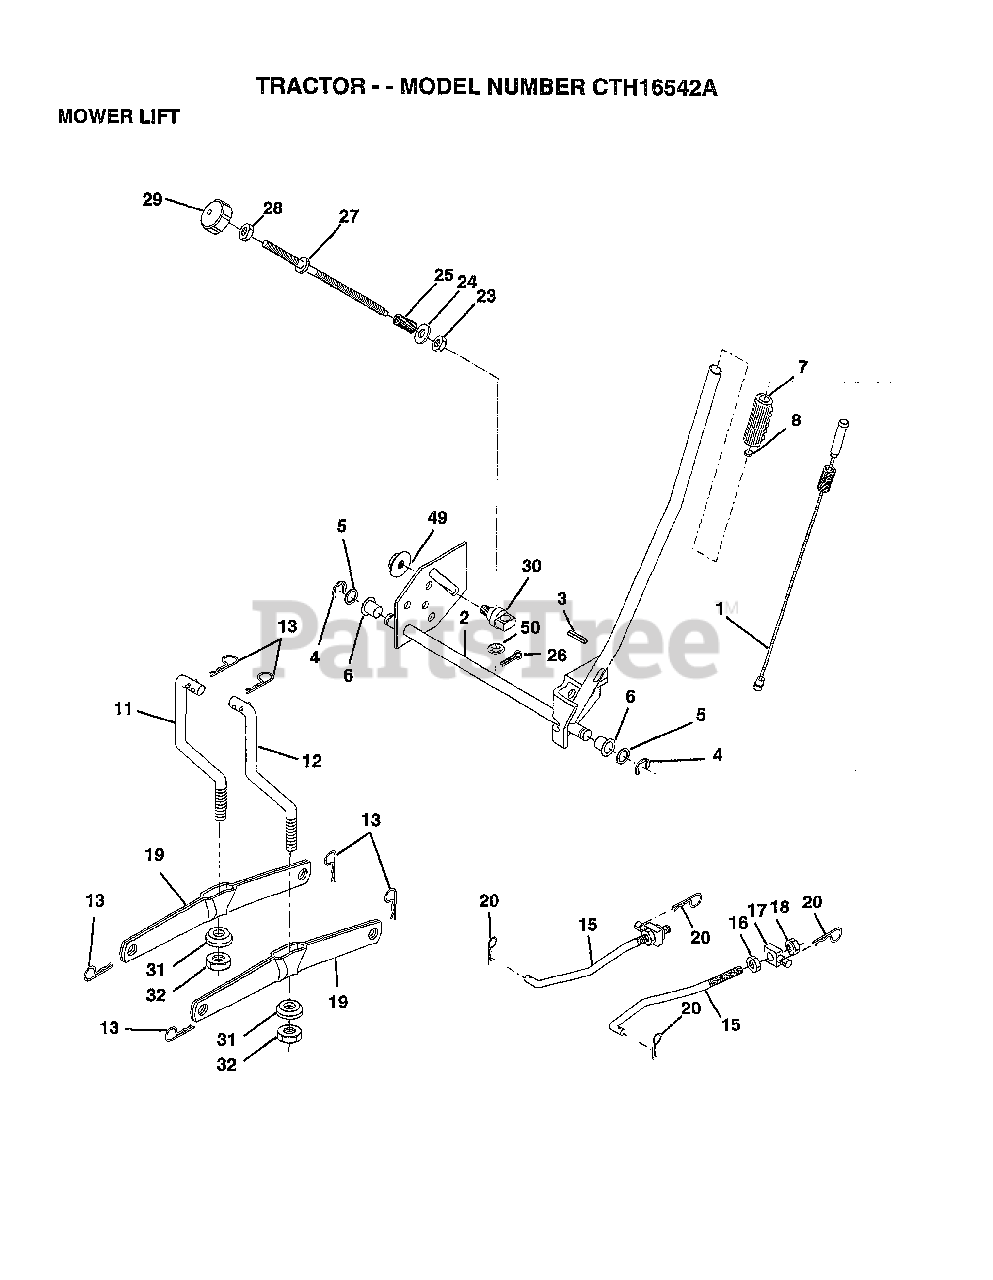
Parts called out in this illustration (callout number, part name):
1	WIRE.ASM.INNER.SP
2	"SHAFT AMS LIFT,RH"
3	PIN GROOVE
5	WASHER
6	NYLON BEARING
7	GRIP
15	LINK.FRONT
16	NUT
17	TRUNION
18	NUT LTV
19	ARM SUSP REAR
20	RETAINER SPRING
23	NUT T
24	WASHER
25	SPRING.COMP.INF.H
27	ROD.ADJ.LIFT
29	KNOB INF 3/8-16
30	TRUNNION
31	BEARING PVT LH
32	NUT.CROWNLOCK.3/8
49	NUT.HXFLG.LOCK.
